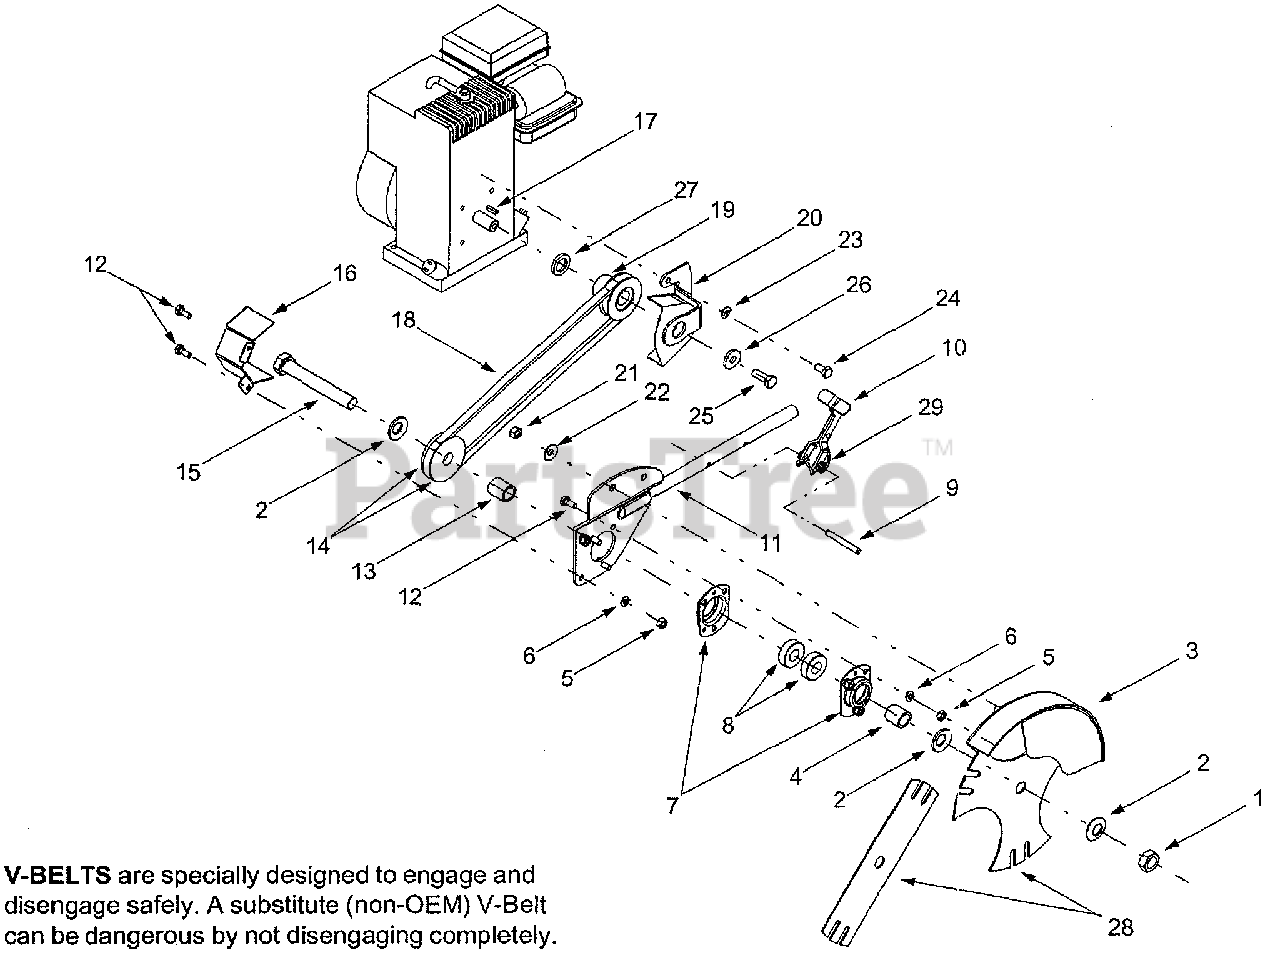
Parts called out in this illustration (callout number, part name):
1	Hex Jam Nut, 518-18
2	Bell Washer, .64 x 1.25 x. 18
5	Hex Nut, 1/4-20
6	Lock Washer, 1/4
7	Bearing Housing
8	Ball Bearing, .62 x 1.38 x .44
9	Spirol Pin, 1/4 x 2.0
10	Adjustment Lever Assembly
13	Spacer, .635 x .88 x 1.03
14	Sheave, .6255 x .6295
15	Hex Cap Screw, 518-18 x 4.5
17	Square Key, 3/16 x .75
18	V-belt, 3/8
19	Engine Pulley, 3/8 x. 75 x 2.38
22	Belleville Washer, .340 x .872
23	Lock Washer, 5/16
24	Hex Cap Screw, 5/16-24 x .625
25	Hex Cap Screw, 3/8-24 x 1.0
26	Flat Washer, .385 x 1.0 x .135
27	Spacer, .753 x 1.25 x. 175
29	Double-torsion Spring
